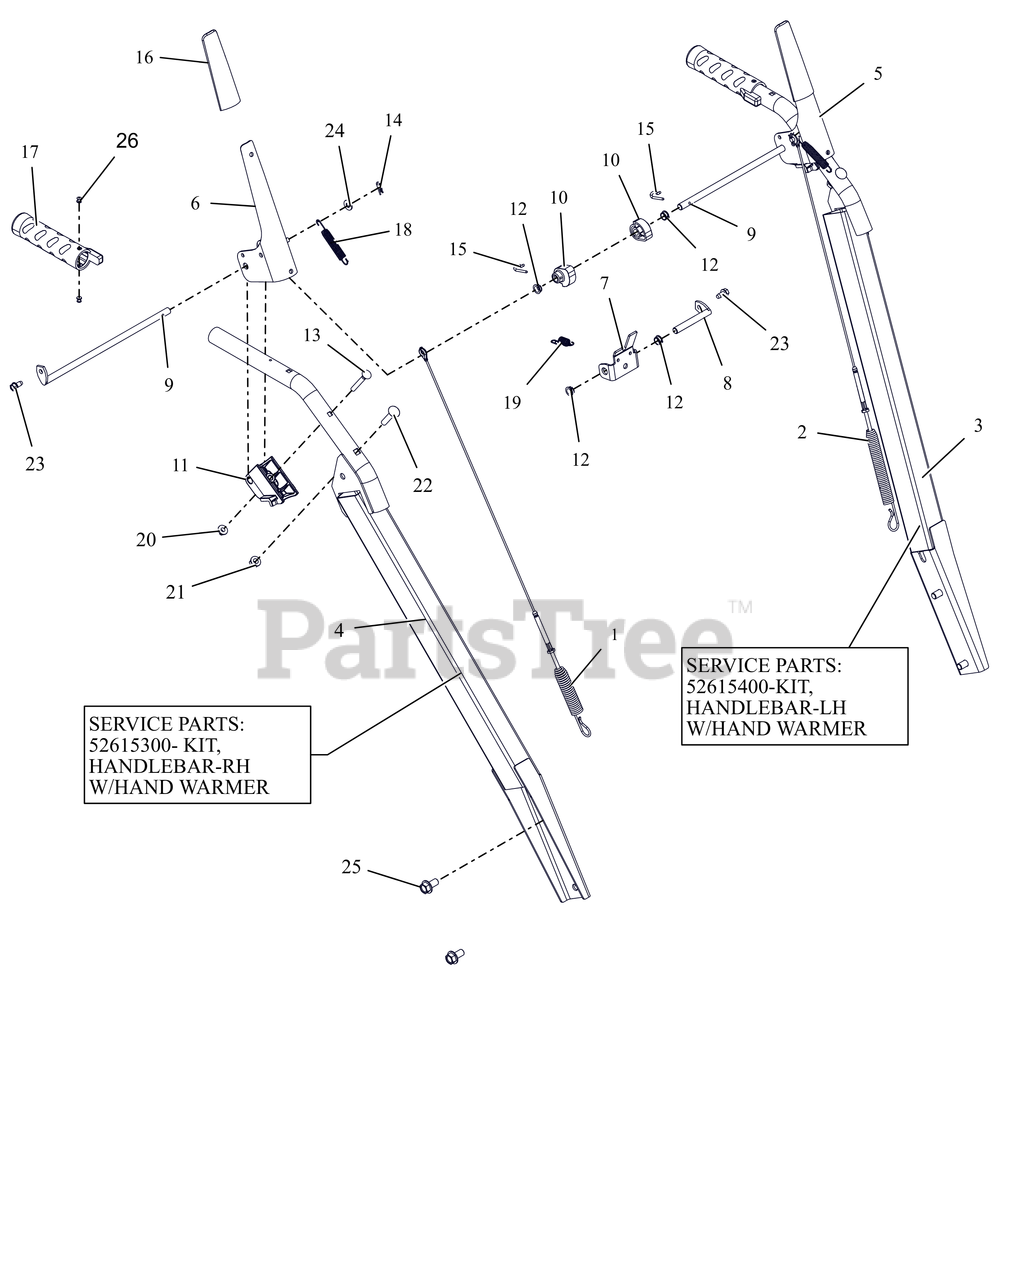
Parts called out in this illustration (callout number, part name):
1	CABLE, AUGER (DELUXE & PRO)
2	CABLE, UPPER TRACTION
3	HANDLEBAR, HEAVYDUTY-PRO LH
3	KIT, HANDLEBAR-LH W/WARM GRIP
4	HANDLEBAR, HEAVYDUTY-PRO-RH
4	KIT, HANDLEBAR-RH W/WARM GRIP
5	LEVER, CLUTCH-LH
6	LEVER, CLUTCH-RH
7	BRACKET, INTERLOCK ARM
8	ROD, PIVOT - INTERLOCK
9	ROD, PADDLE MOUNT - PRO
10	CAM, INTERLOCK
11	BLOCK, CLUTCH PADDLE
12	BUSHING, POLYLINER-.38 SNAPIN
13	BLT-RDHDXLSQNK .25-20X2.0 G5YZ
14	PIN, HAIR #178 .06X.77 ZCC
15	PIN, SPRING CLIP
16	SLEEVE, CLUTCH PADDLE-GRAY
17	GRIP,HEATED HANDLE-GRAY
18	SPRING, EXTENSION
19	SPRING-EXT .047X.438X1.45
20	NUT-LK-CTR-FLG .25-20 ZC120
21	NUT-LK-TOP-FLG .312-18 GF ZCC
22	BLT,RHSN .31-18X1.50 G5 ZCC
23	SCR-TAP .25-20X.50 HWH ZCC
24	WSHR,FLT .281X.625X.065 ZCC
25	BLT-SERHFWH .38-16X.75 YWZC
26	RVT-POP #43 .125X.313 STL ZINC
